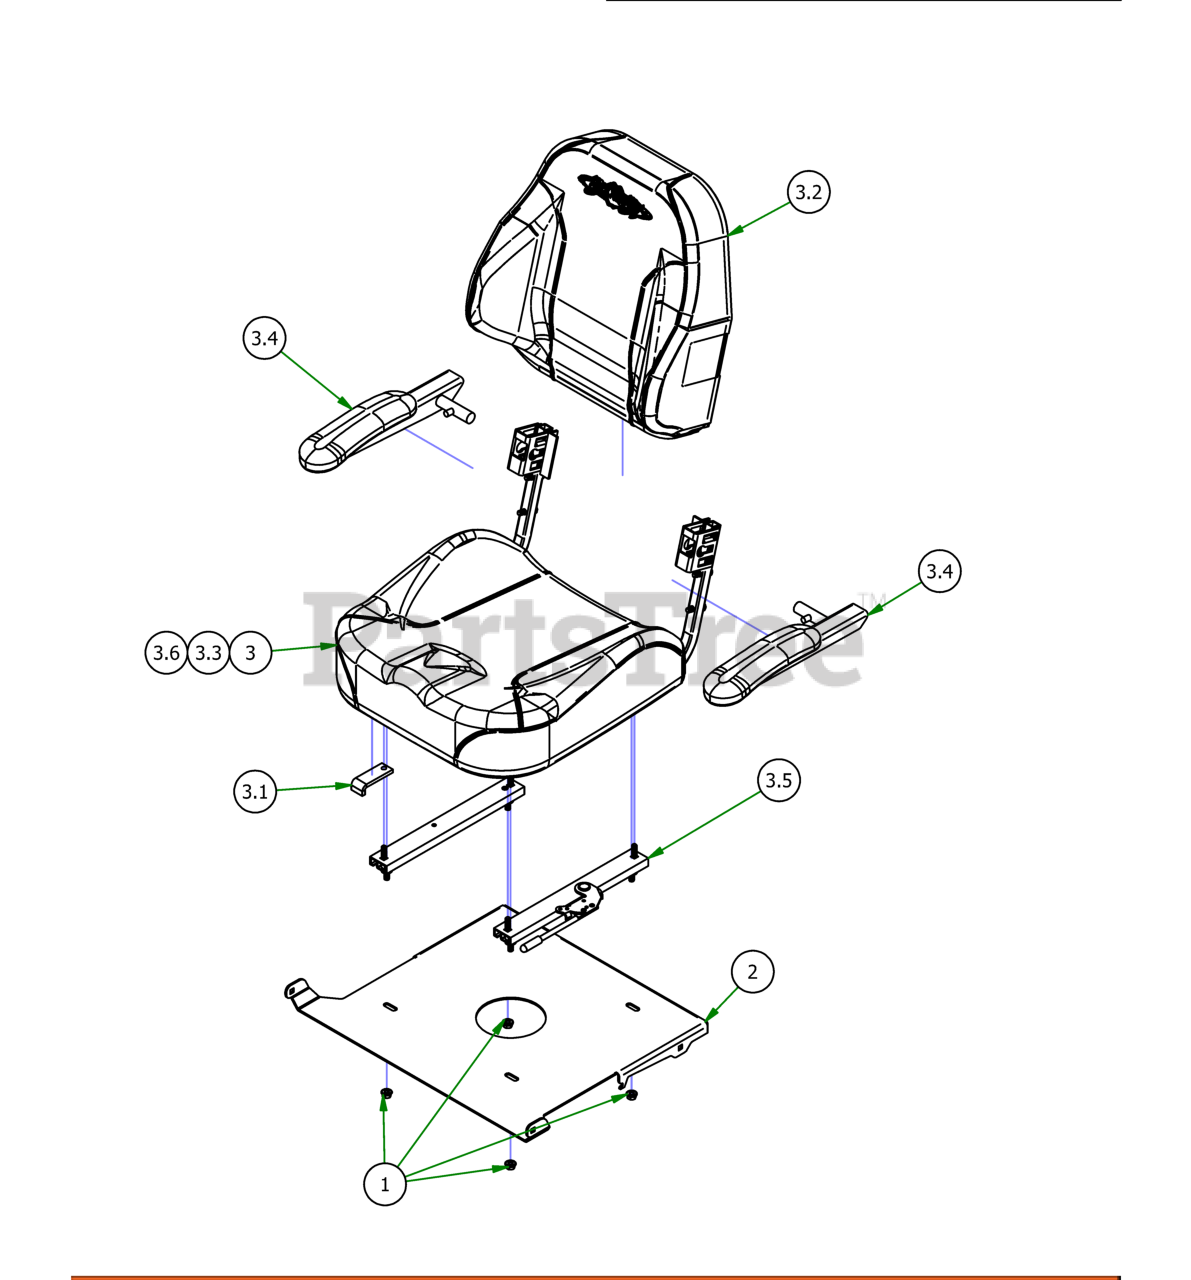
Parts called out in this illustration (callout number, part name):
1	5/16-18 NYLON INSERT FLANGE LOCKNUT ZINC
2	Seat Plate 2016
3	2017 ZT Seat/ 2019 Magnum Kaw
3.1	Black Seat Stop from Seat King
3.2	2017 ZT Back Cover For 071-2040-17
3.3	2017 ZT Seat Cover For 071-2040-17
3.4	Arm Rest (Pair)
3.5	Seat Rails for Outlaw Seat/2020 ZT Elite/ZTAvenger
3.6	2014 Magnum Seat Switch
